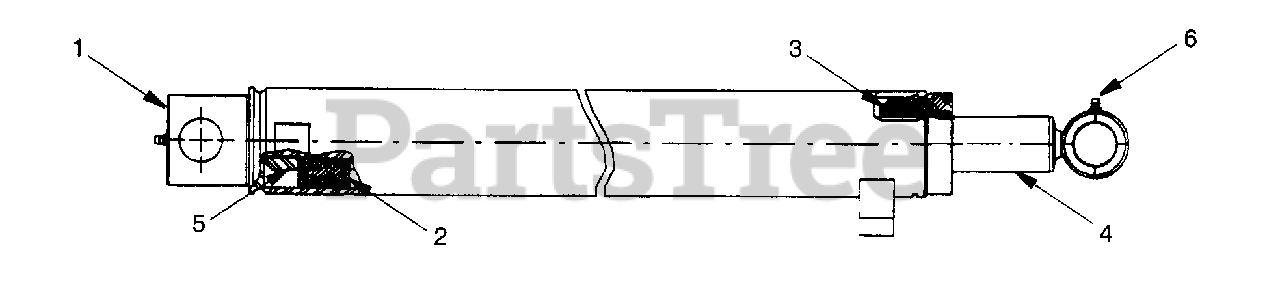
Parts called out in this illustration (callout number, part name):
1	Complete Assembly
3	Head Gland
6	Lube Fitting
